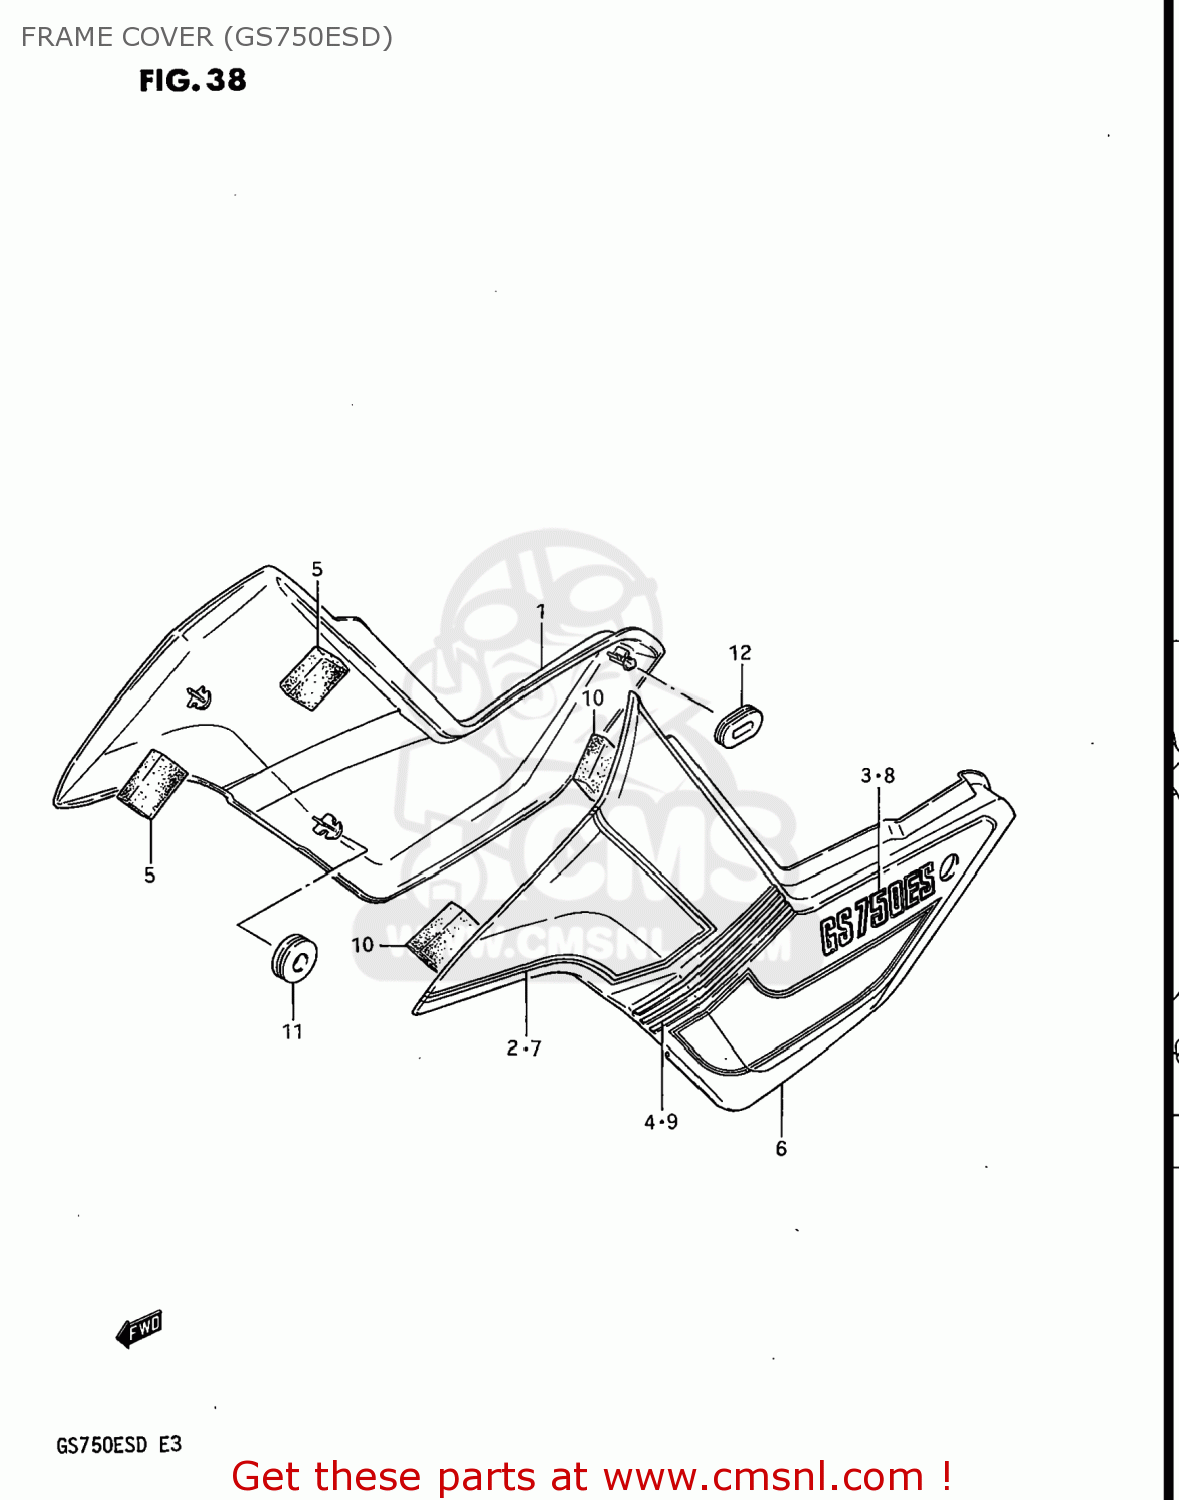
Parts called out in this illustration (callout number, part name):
1	COVER,FRAME,RIGHT
2	TAPE SET,FRAME COVER
3	EMBLEM,FRAME COVER
4	DENT,FRAME COVER,RIGHT
5	CUSHION
6	COVER,FRAME,LEFT
7	TAPE SET,FRAME COVER
8	EMBLEM,FRAME COVER
9	DENT,FRAME COVER,LEFT
10	CUSHION
11	CUSHION
12	CUSHION
